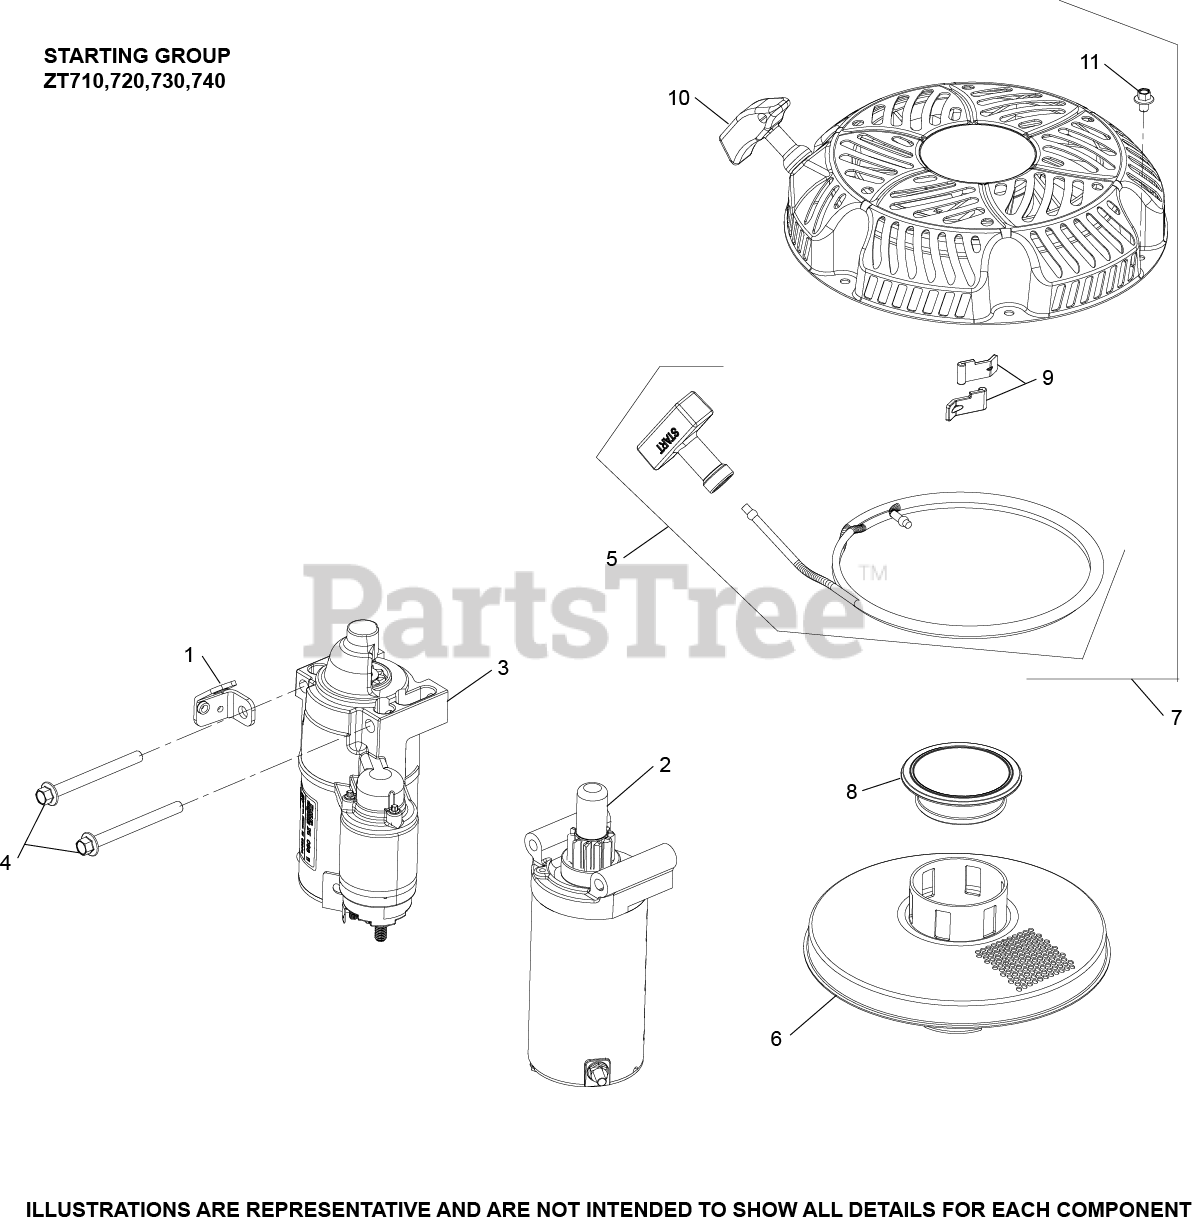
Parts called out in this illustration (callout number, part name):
1	BRACKET, OIL FILL TUBE
4	SCREW, FLG M8X1.25X80
5	KIT, ROPE AND HANDLE
6	SCREEN ASSEMBLY, STARTER DRIVE CUP
7	RETRACTABLE STARTER ASSEMBLY
9	KIT, PAWL REPAIR
10	HANDLE, RECOIL STARTER
11	SCREW, M6 X 8 HEX FLANGE HEAD
